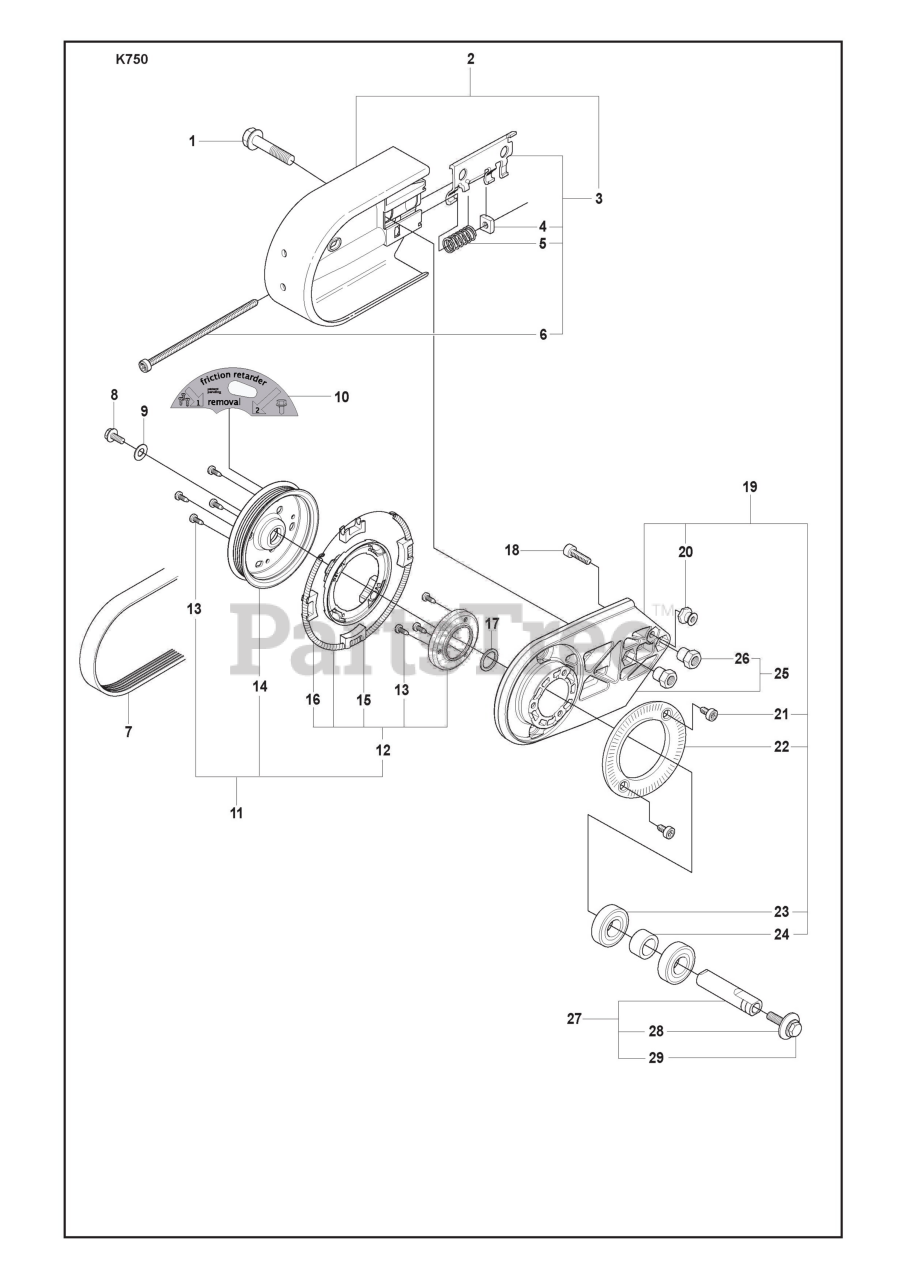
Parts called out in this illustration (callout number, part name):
1	COLLAR SCREW
2	BELT GUARD
3	BELT TENSIONER ASSY
5	COMPRESSION SPRING
9	WASHER STEEL
11	PULLEY WITH RETARDER
12	RETARDER CPL
14	PULLEY
15	BRAKE SHOE
17	WASHER STEEL
19	BEARING HOUSING
20	TORSION STOP
22	RATCHET FLANGE
23	BALL BEARING
24	SPACING SLEEVE
25	BEARING HOUSING
27	SHAFT
28	WASHER
29	COLLAR SCREW
